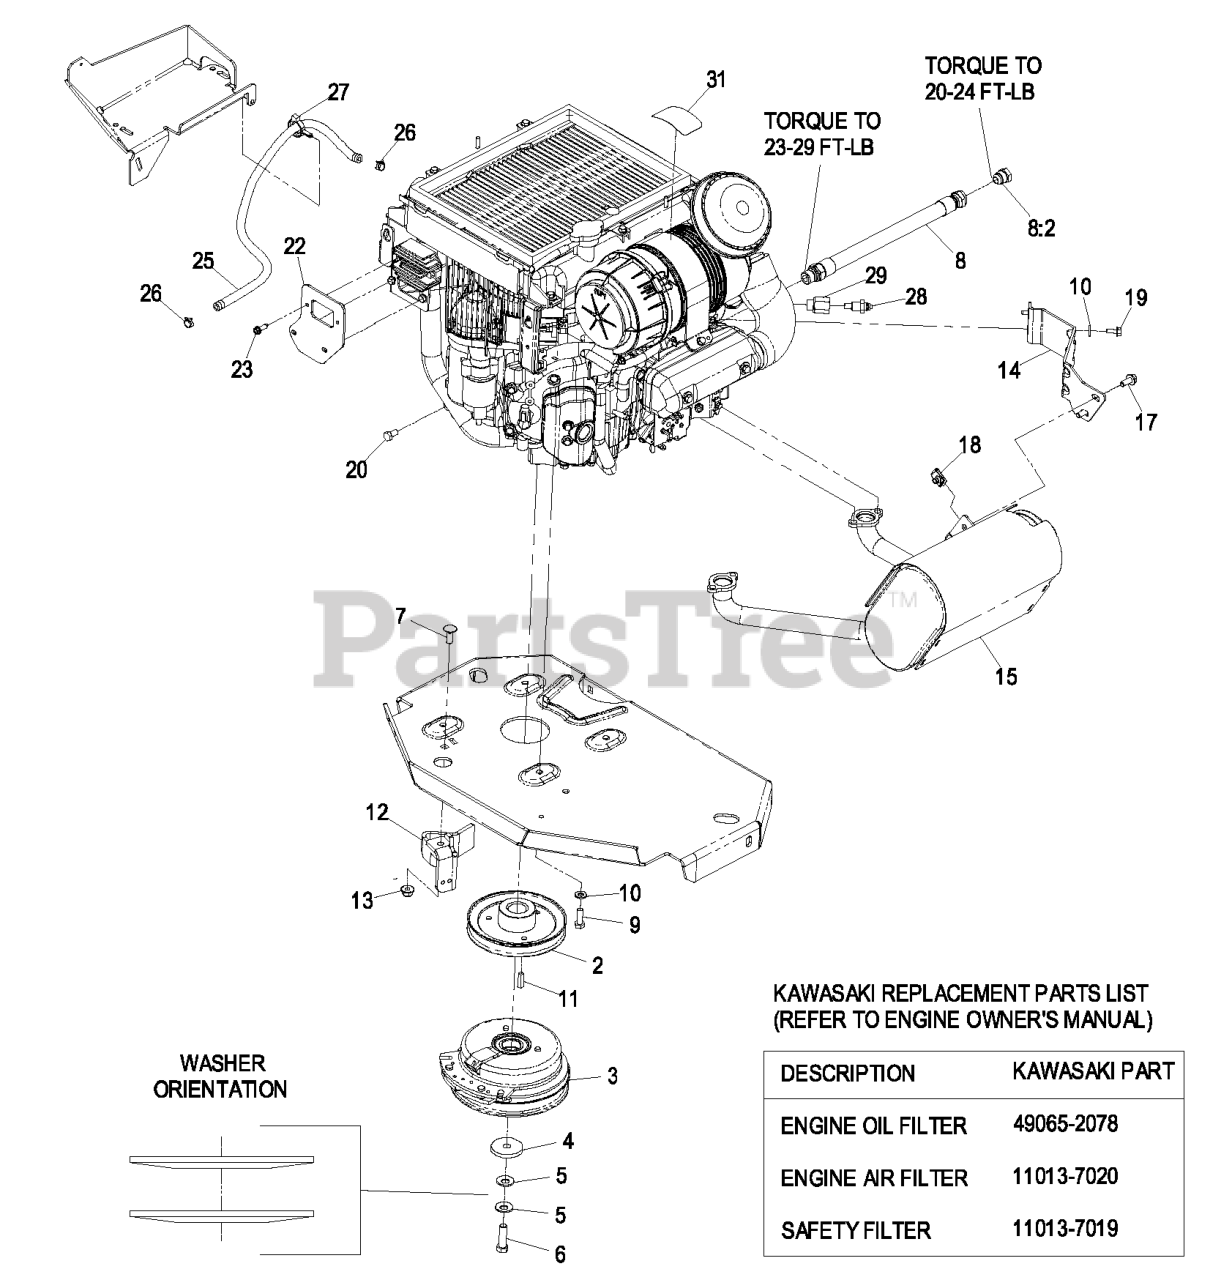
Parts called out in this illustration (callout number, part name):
2	SHEAVE
3	CLUTCH KIT
4	WASHER-CLUTCH
5	WASHER-SPRING
6	SCREW-HH 7/16-20 X 1 1/2 W/LOCTITE
7	SCREW-CARR
9	SCREW-HH
10	WASHER-SPRING
12	CLUTCH-ANCHOR
13	NUT-HF, NI
14	BRACKET,MUFFLER 26LKA
17	SCREW-HHF
19	SCREW-HHF
20	SCREW-HH
22	PLATE,RECTIFIER MOUNT, LK
23	SCREW-HWHTF
25	HOSE-FUEL
26	CLAMP-HOSE
27	CLAMP-HOSE
28	SENDER-TEMPERATURE
31	DECAL,SHELL COOLANT
